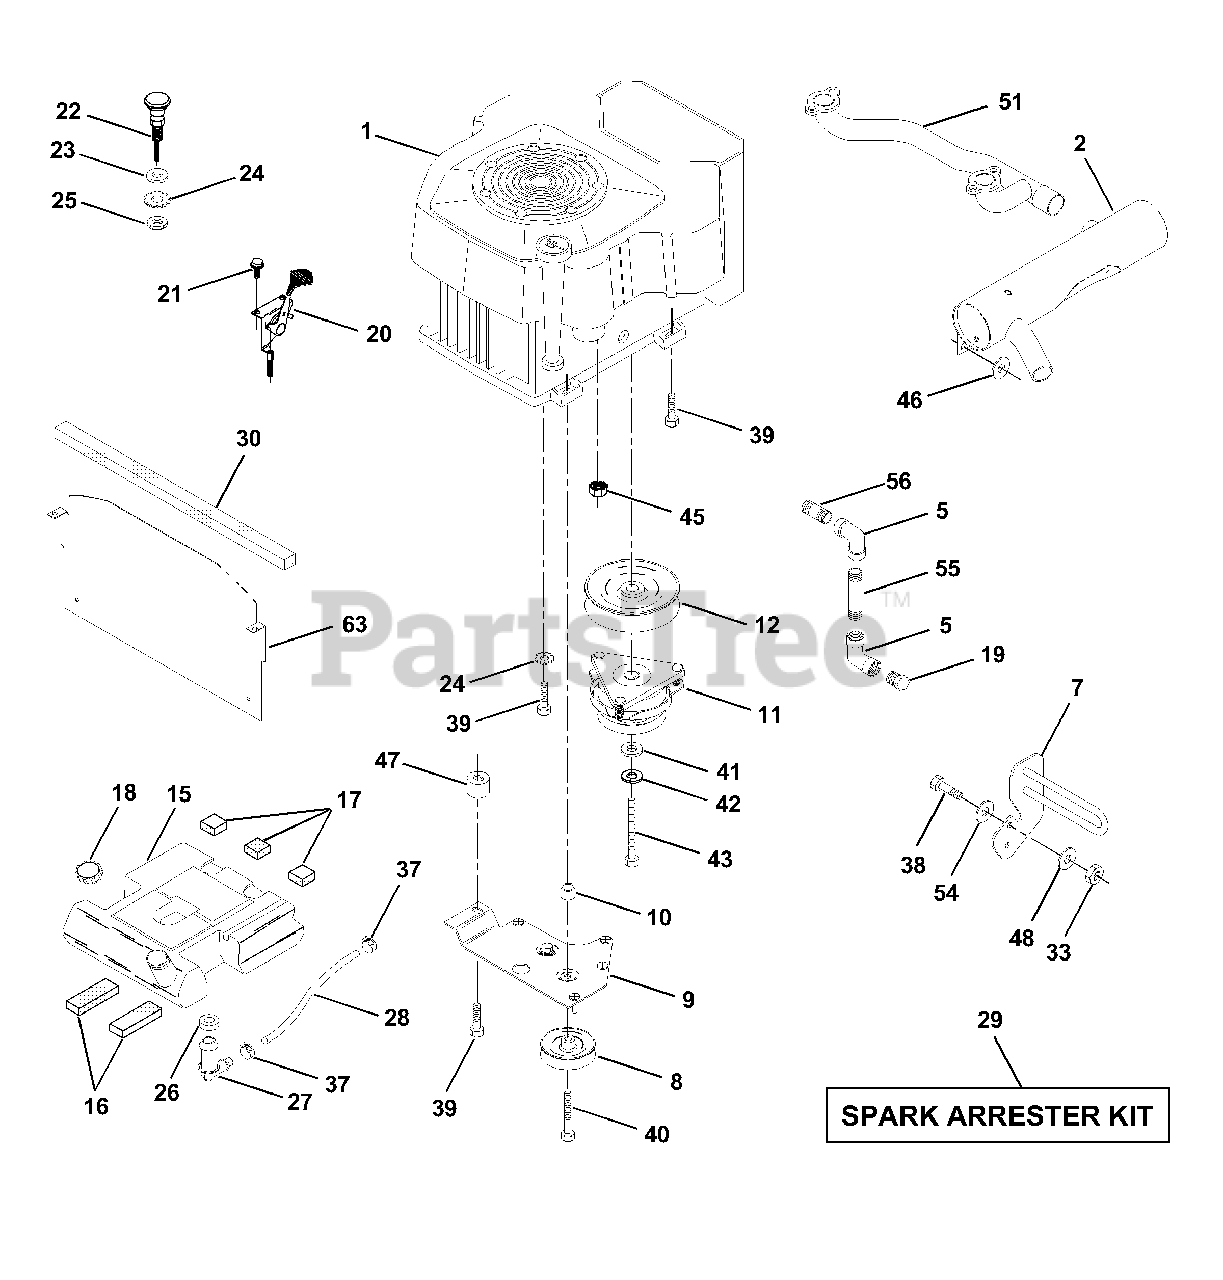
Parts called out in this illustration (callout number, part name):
2	Muffler VGT Cylinder
5	Elbow STD 90 Degree 3/8-18 NPT
7	Muffler Assembly Guard
8	Pulley V-Idler
9	Stop Keeper Asm VGT
11	Clutch Electric
12	Pulley Engine VGT Elect Clutch
15	Tank Fuel W/Sym Vented
16	Pad Spacer
17	Pad Spacer
18	Cap Asm Fuel W/Sym Vented
19	Plug Oil Drain
20	Control Throttle
21	Screw Hex Thd Cut 1/4-20 X 5/8
22	Control Choke
23	Washer 13/32 X 13/16 x 16 Ga
24	Washer Ext Tooth 3/8
25	Nut Fin Hex 3/8 - 24 UNF
26	Bushing
27	Stem Tank Fuel
28	Fuel Line
29	Spark Arrester Kit
30	Strip Foam 18"
33	Nut, Hex W/Ins. 3/8-16 UNC
37	Clamp Hose
38	Bolt, Fin Hex 3/8-16 UNC x 1-1/2
39	Screw TT 3/8-16 x 2-1/4 UNC
40	Screw TT 3/8-16 x 4 UNC
41	Washer 1-1/2 OD X 15/32 ID X .250
42	Washer Lock 7/16
43	Bolt Hex 7/16-20 X 4-1/4 Ga 5
45	Nut Flange 1/4-20 Starter Nut
46	Washer 13/32 x 1 x 16 Ga.
47	Spacer Engine
48	Washer 13/32 x 1-1/4 x 7 Ga.
51	Pipe Crossover
54	Washer Flat 13/32 x 7/8 x 14 Ga.
55	Nipple, Pipe 3/8 NPT x 4-1/2
56	Nipple, Pipe 3/8 NPT x 1.00
63	Shield, Heat VGT YP/Husq.
